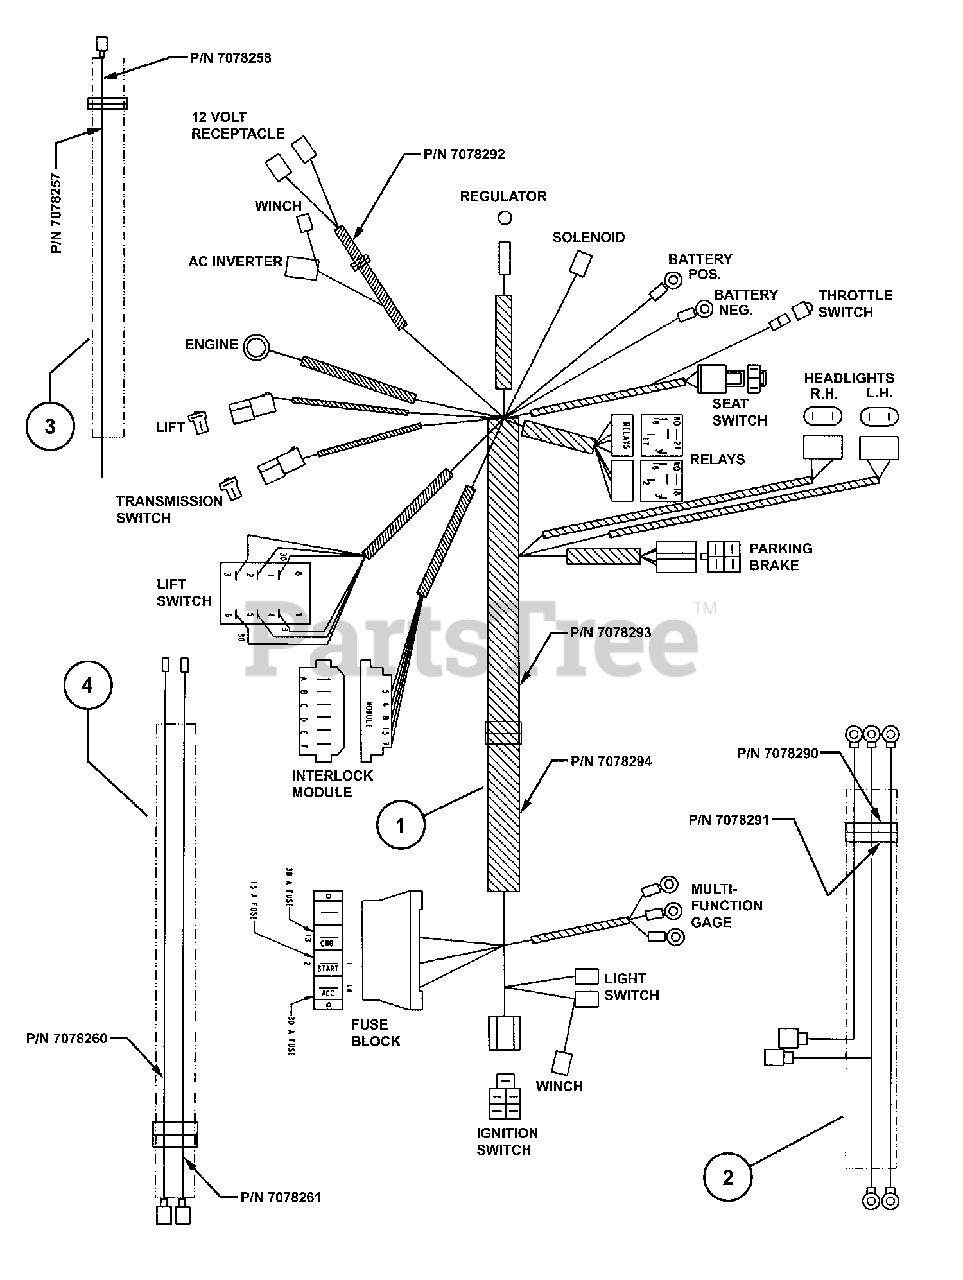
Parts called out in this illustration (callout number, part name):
1	WIRING HARNESS, UV2, Main
2	WIRING HARNESS, UV2, Speed/Fuel
3	WIRING HARNESS, UV2, Tachometer
4	WIRING HARNESS, Winch
